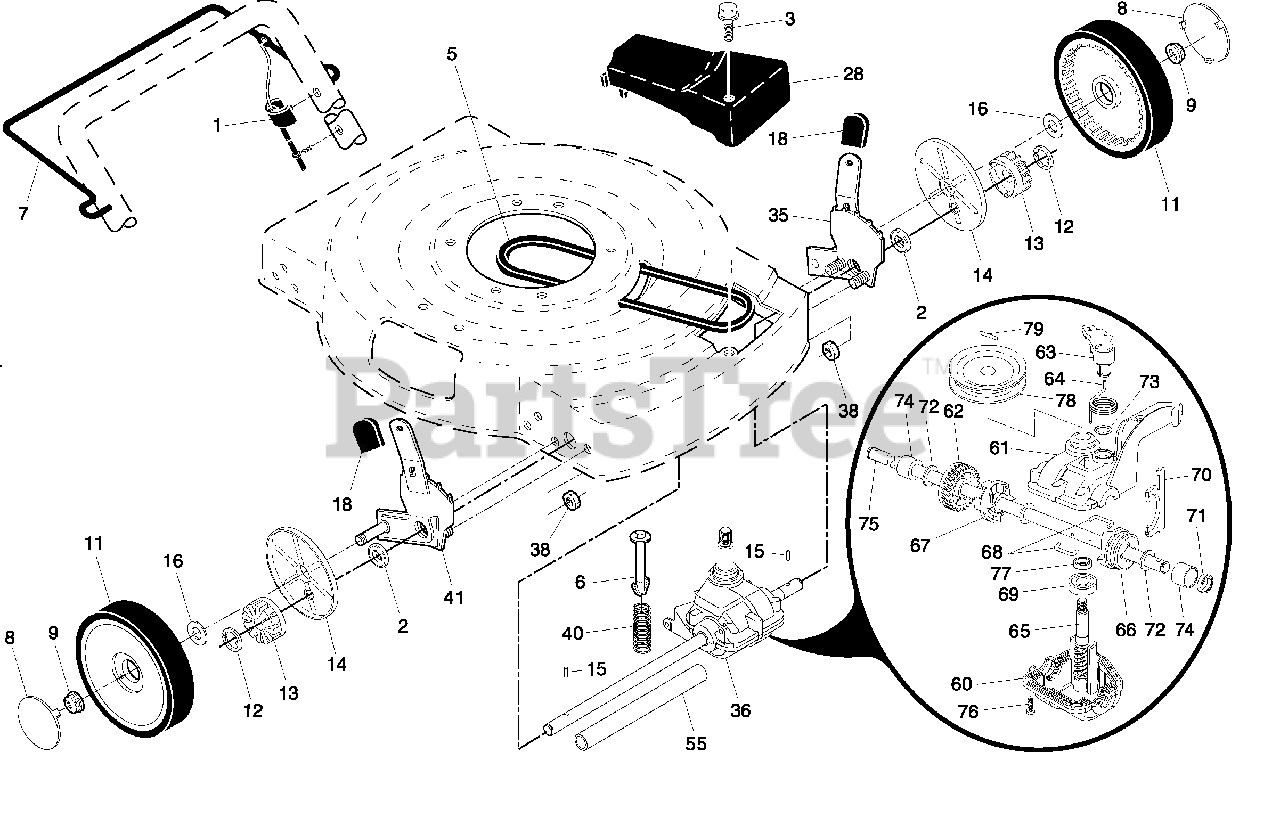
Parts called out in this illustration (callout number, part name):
1	Drive Control Cable Assembly
2	Bearing, Wheel Adjuster
3	Pan Head Tapping Screw #10-24 x 2-3/4
6	Spring Retainer
7	Control Bar, Drive
8	Hubcap
9	Locknut, Hex
11	Wheel & Tire Assembly
12	E-Ring
13	Pinion
14	Dust Cover
15	Pawl, Drive
16	Washer
18	Selector Knob
28	Drive Cover
35	Kit, Wheel Adjuster, LH
36	Gear Case Assembly, Complete
38	Locknut, Hex 1/4-20
40	Spring
41	Kit, Wheel Adjuster, RH
55	Driveshaft Cover
60	Case, Lower
61	Case, Upper
62	Gear, 27 Teeth
63	Lever, Clutch
64	Spring, Return
65	Shaft, Input
66	Dog, Movable
67	Dog, Fixed
68	Wire, Formed
69	Bearing, Ball
70	Fork, Shift
71	Seal, Output Shaft
72	Washer
73	Seal, Case
74	Bushing
75	Shaft, Output
76	Screw
77	Seal, Input Shaft
78	Drive Pulley
79	Pin, Retainer
